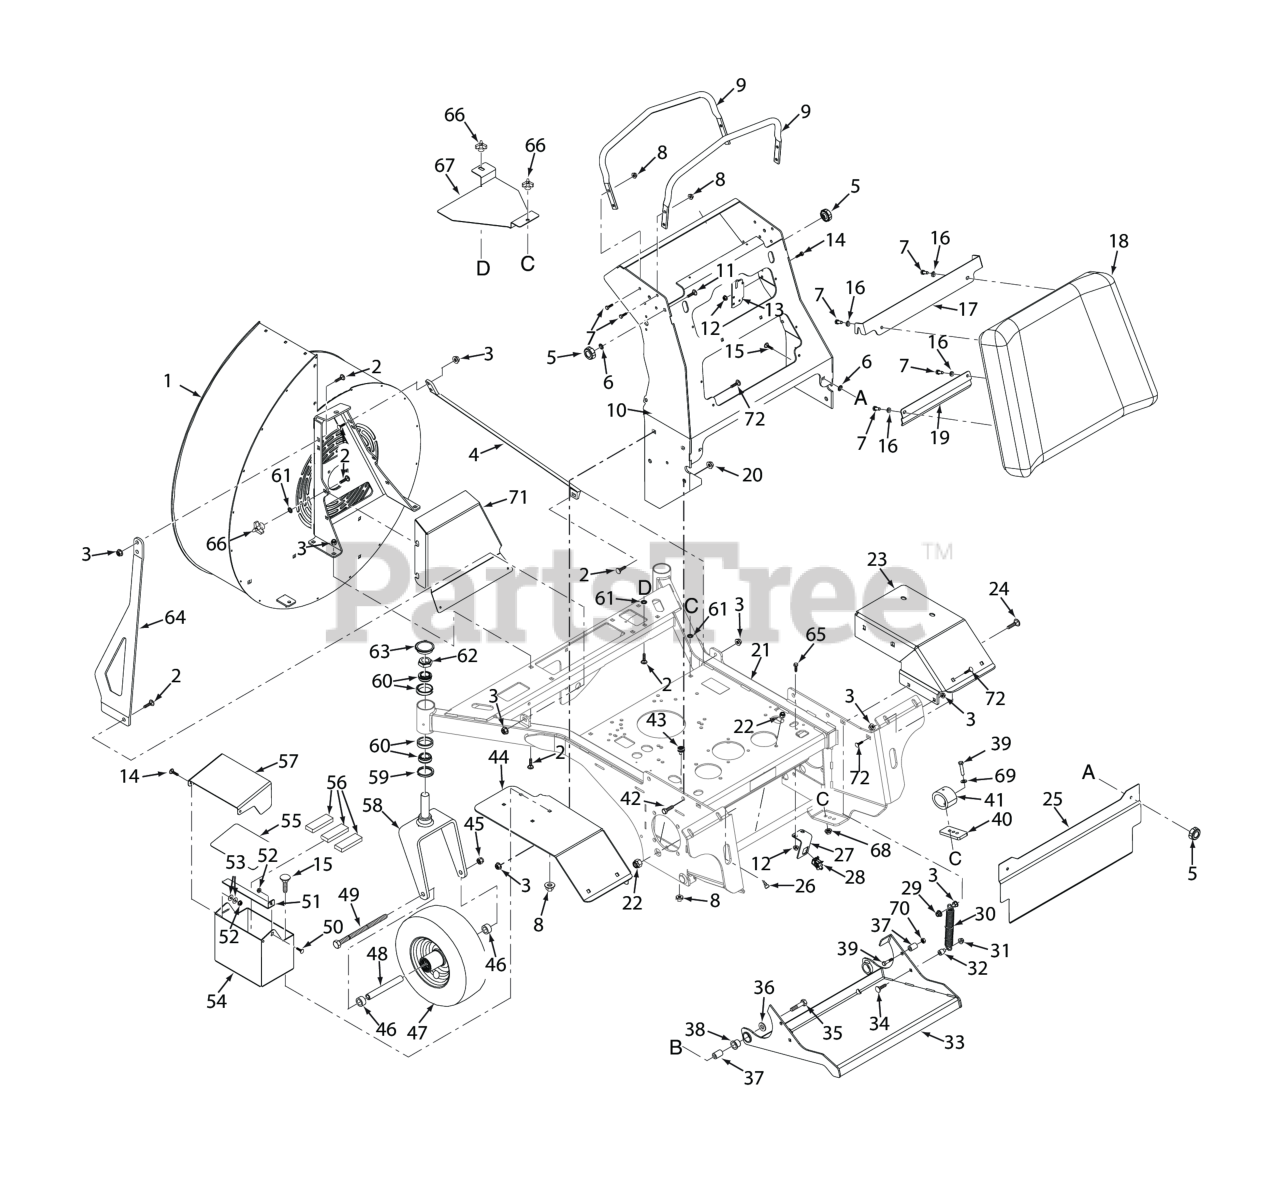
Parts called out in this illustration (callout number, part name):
1	Blower Housing, With Decal
2	Carriage Bolt, 3/8-16 x 1.0"
3	NUT, 3/8-16 SERRATED FLANGE HEX HEAD
4	RH Support Bar, Blower
5	Knob, 5/16-18
6	Nut, Push-On 5/16-18
7	BOLT, SERRATED FLANGE HEX HEAD 5/16-18 X 3/4"
8	Nut, Serrated Flange 5/16-18 (Right Front Engine Mounting, Briggs and Kohler Only)
9	Reference Bar
10	Handlebar Weldment, SVRII
11	Bolt, Carriage 5/16-18x1" (large frame units only)
12	NUT, 1/4-20 SERRATED FLANGE HEX HEAD
13	Bracket, Neutral Switch
14	BOLT, HEX HEAD, 1/4-20 X 3/4 GR.5
15	Bolt, 5/16-18 x .75 RHSN Carriage
16	Lockwasher, 5/16 (.317 x .586 x .078) Helical Spring
17	Bracket, Knee Pad - Upper
18	Operator Pad Assy, SVRII (INCL. 10,11,12,13)
19	Bracket, Knee Pad - Lower
20	Locknut, 1/2-13 Spiral Lock
21	Mainframe Assembly, With Decals
22	HEX NUT, ELASTIC STOP LOCK, 3/8-16
23	Fender, RH
24	Bolt, RDHD Carr. 3/8-16 x 1-1/2 (52" & 61")
25	Guard, Foot -SVRII
26	BUMPER, PLUG
27	Mounting Bracket, Footplate Switch
28	SWITCH, NEUTRAL INTERLOCK
29	Nut, Flange Elastic Stop Nut, 3/8-16
30	Spring,Counter Balance
31	Nut, Flange Head Elastic Stop 5/16-18
32	Spacer, Pump Dampener
33	Footplate Assy, SVRII (Incl. #35)
34	Bolt, Carriage 5/16-18 x 1-1/2"
35	Capscrew, Hex Head 3/8-16 x 2.0"
36	Flatwasher, 3/8" Special (.391 x .938 x .105)
37	Yoke, Front Caster Wheel
38	Bearing, Pivot
39	Bolt, Hex Head 3/8-16 x 1-3/4" (Kohler EFI)
40	Riser
41	Isolator, Footplate
42	Capscrew, 1/2-13 x 1" Serrated Flange Hex Head
43	Bumper, Rubber 5/16-18 x 5/8"
44	Fender, LH
45	HEX LOCKNUT, ELASTIC STOP, 1/2-13
46	Spacer, Caster Wheel
47	Wheel Assy, 61V, 72V (Incl. 20, 54, 55)
48	Sleeve, Caster Wheel (48 / 52)
49	Bolt, Hex Head 1/2-13 x 7-1/2" (48"/52")
50	Bolt, Carriage 1/4-20 x 1/2"
51	Battery Box Latch
52	HEX, NUT, ELASTIC STOP LOCK, 1/4-20
53	Flatwasher, 1/4" (.312 x .750 x .065")
54	Battery Box, Lower
55	Insulation, Battery Cover (Gas Only)
56	PAD, BATTERY SUPPORT
57	Battery Box, Upper
58	Yoke Weldment, (Black))
59	Seal, 2.00" O.D. x 1.625" Bore
60	Bearing Set
61	Nut, Push-On - 3/8" Dia.
62	Nut, Elastic Stop 1.0"-14
63	Cap, Grease
64	LH Support Bar, Blower
65	Serr. Fl. Hex Head CPSCR, 1/4-20 x 3/4"
66	Wing Nut, 3/8-16 (Small) Top side
67	Belt Cover, Gearbox
68	Nut, Flange Elastic Stop Nut, 3/8-16
69	Flatwasher, 3/8 (.406 x .812 x .065)
70	Bolt, Hex Head 3/8-16 x 1" Ser. Flg.
71	Belt Cover, Blower
72	Bolt, Carriage 3/8-16 x 3/4"
